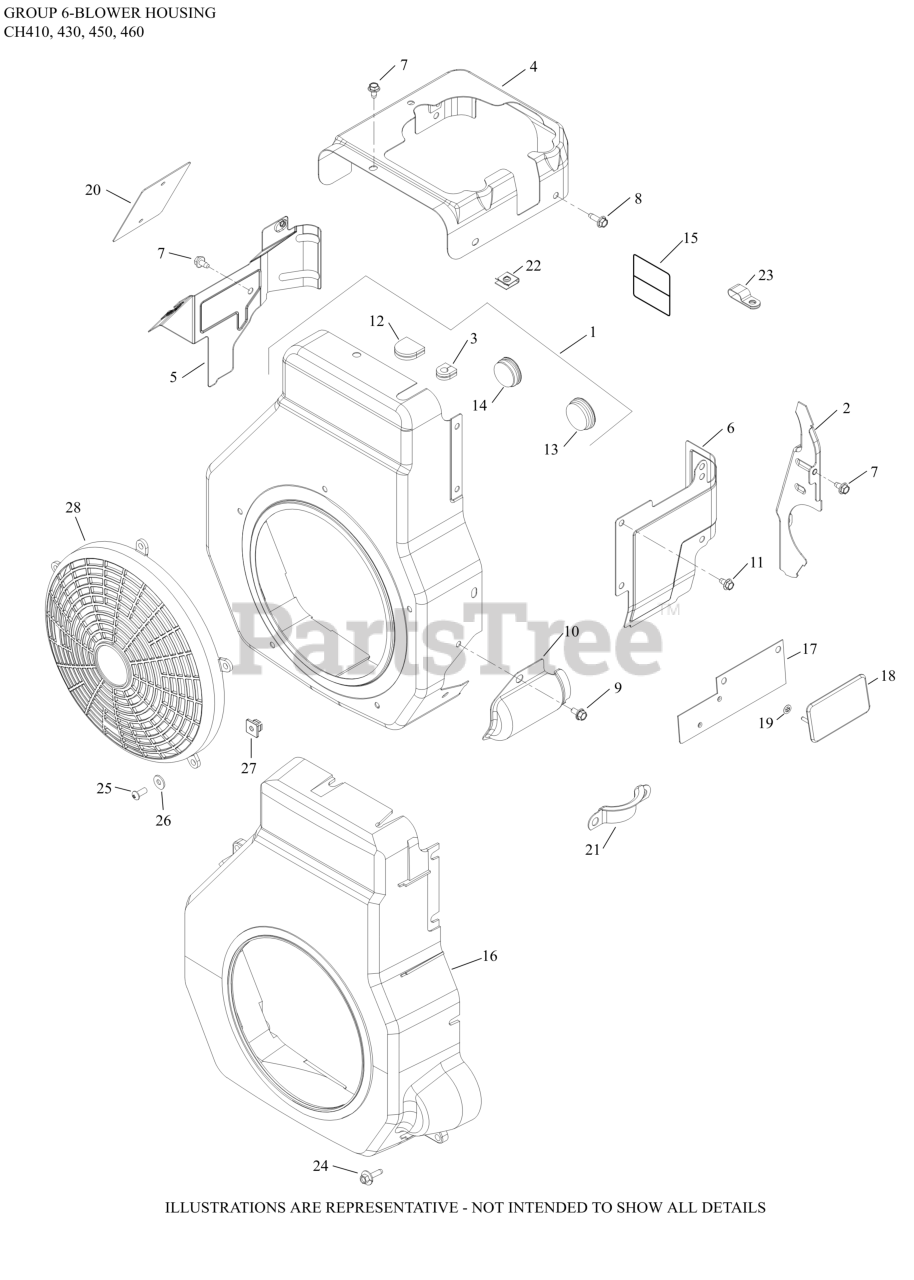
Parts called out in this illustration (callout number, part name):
1	KIT, BLOWER HOUSING
2	PLATE, BACKING
3	GROMMET-DISCONTINUED
4	BAFFLE, CYLINDER HEAD
5	BAFFLE, INTAKE SIDE
6	BAFFLE, CYLINDER-(#DSC)
7	SCREW, FLG THD FRM M5X.8X10
8	SCREW,FLG THD FRM M5X0.8X16-(#25086398S)
9	SCREW, HVY FLG M5X.8X10
